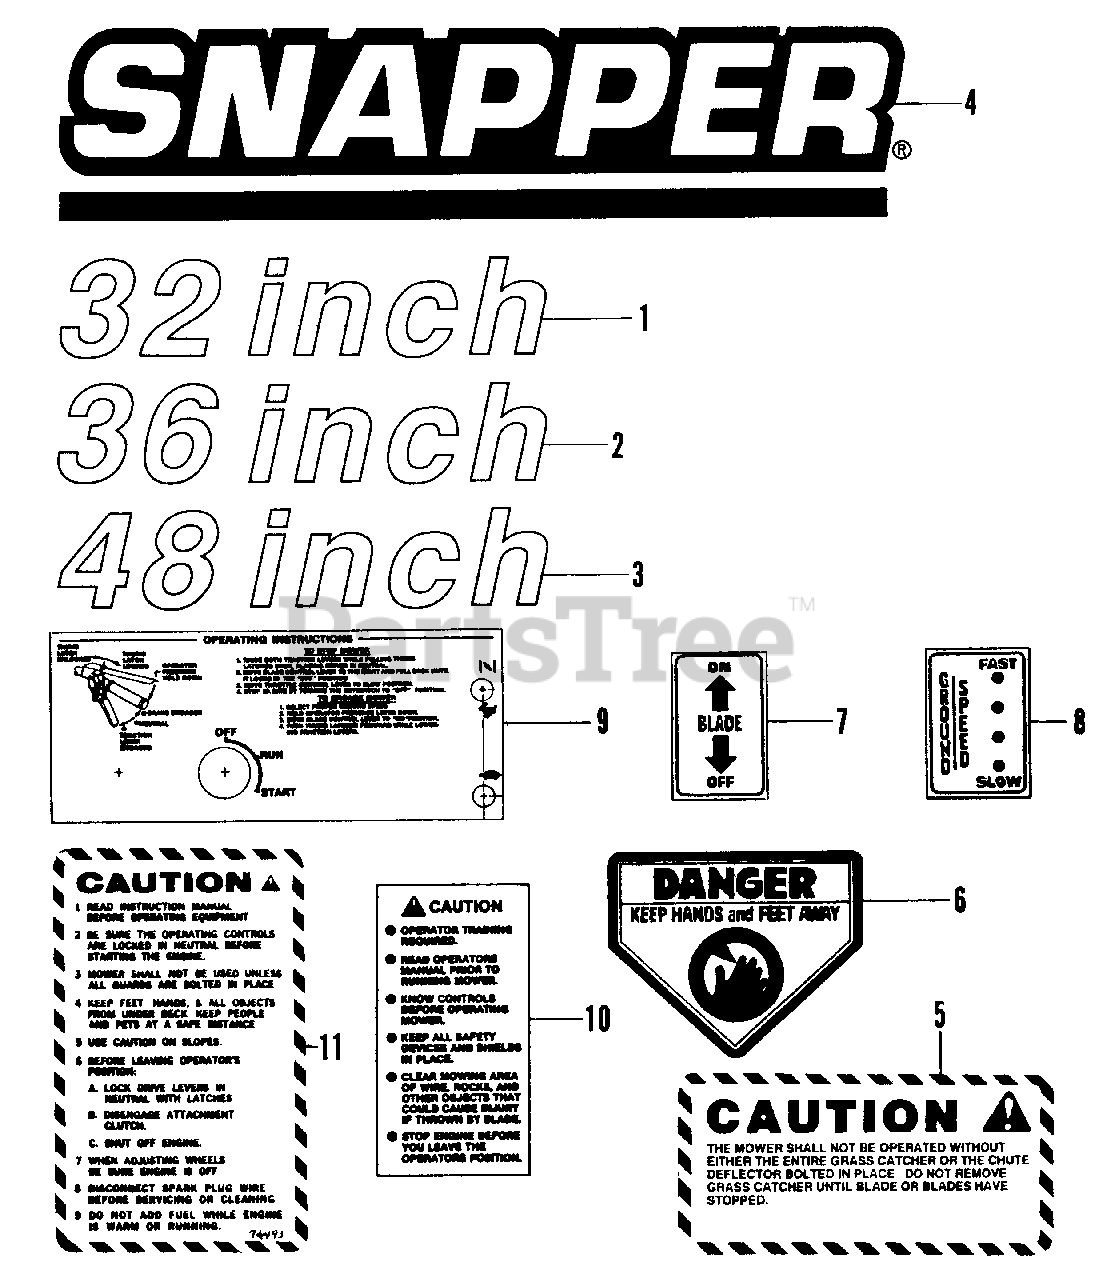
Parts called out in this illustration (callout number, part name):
1	DECAL, 32 inch
2	DECAL, 36 inch
3	DECAL, 48 inch
4	SNAPPER, Medallion
5	CAUTION Decal
6	CAUTION CPSC Decal
7	BLADE Decal
8	GROUND SPEED Decal
9	CONTROL PANEL Decal
10	CAUTION Decal
11	CAUTION Decal
